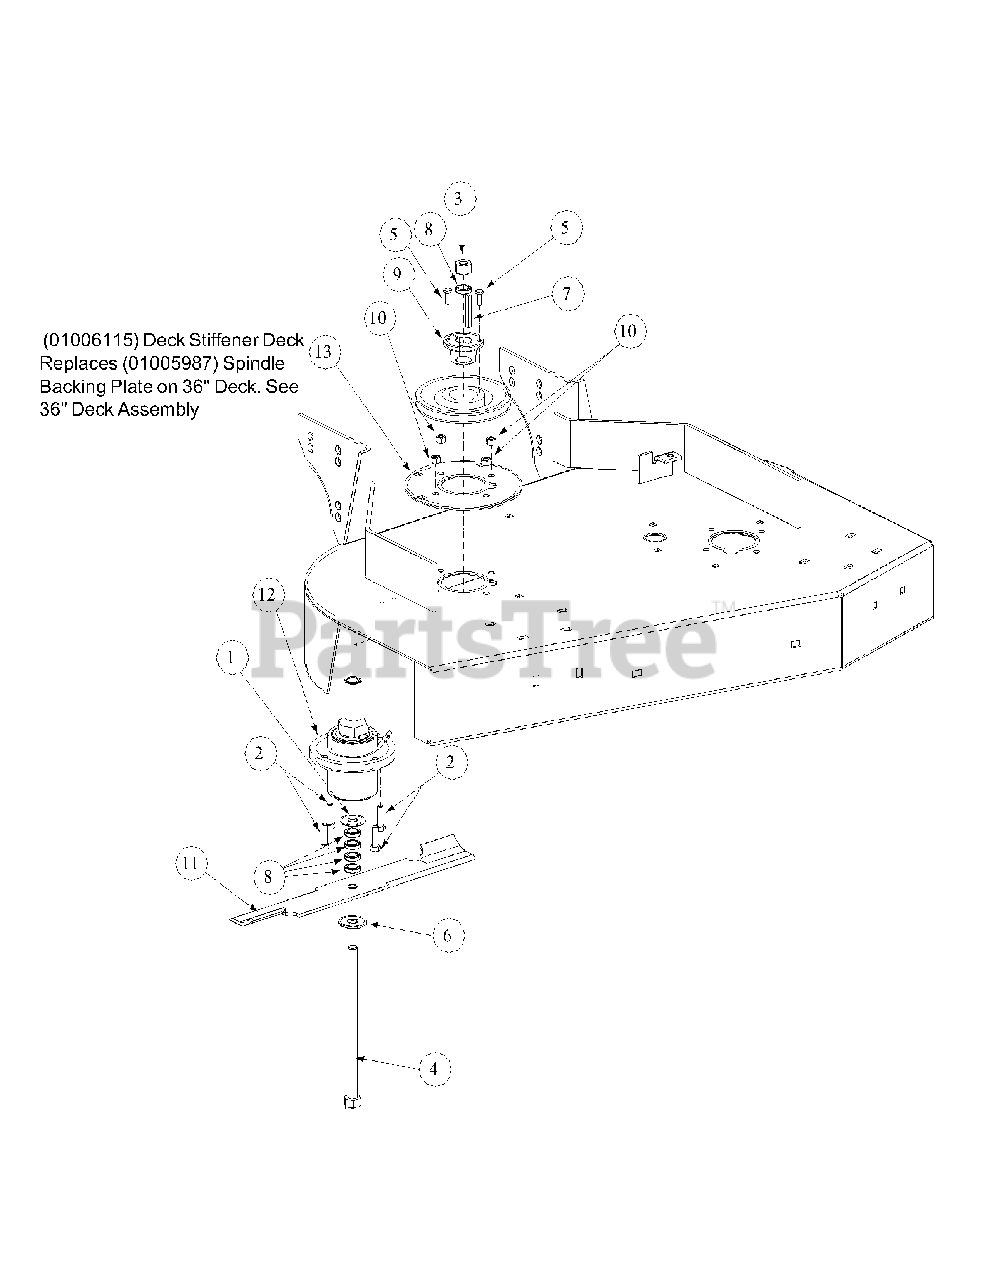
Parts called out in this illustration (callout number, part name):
1	Flat Washer, 1-1/2 x 5/8 x .05
2	Hex Cap Screw, 3/8-16 x 1-1/4
3	Hex Nut, 5/8-11
4	Hex Cap Screw, 5/8-11 x 9-1/2
5	Hex Cap Screw, 1/4-20, .75
6	Flat Washer, 5/8 Zinc
7	Key Stock, 1/4 x 1/4 x 2
8	Blade Spacer, 5/8 ID, 1/4 Thick
10	Lock Nut, 3/8-16
11	Blade 18"
12	Spindle Assembly
13	Plate, Spindle Backing
